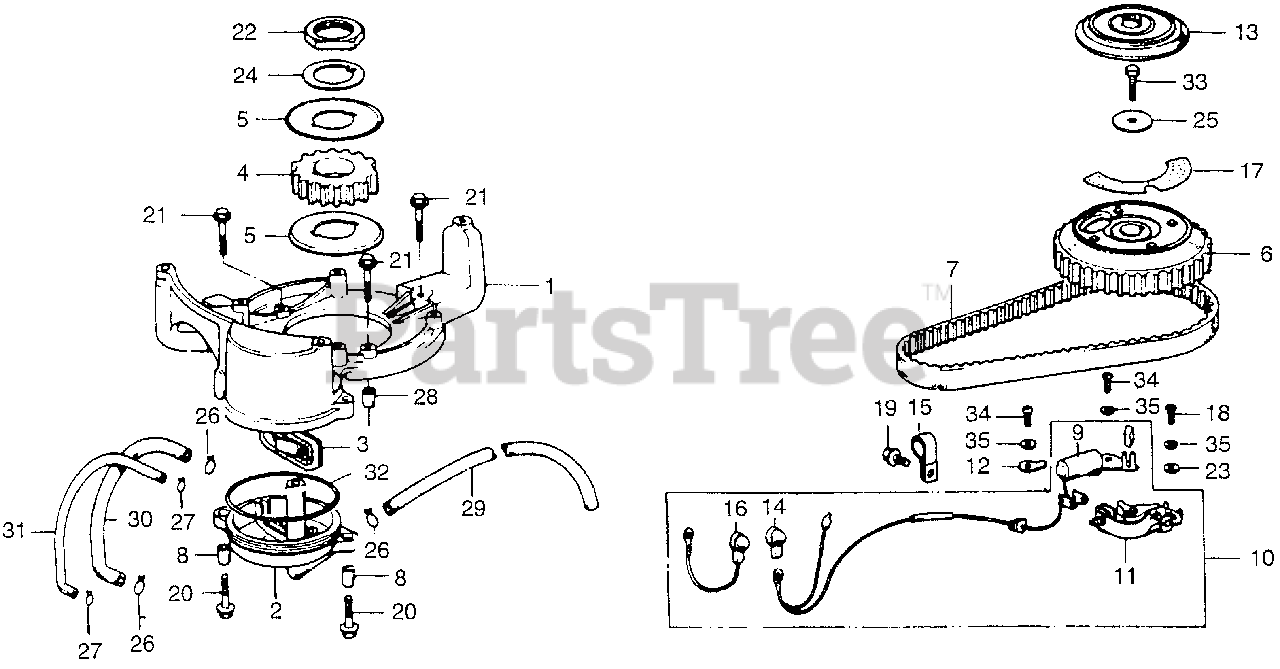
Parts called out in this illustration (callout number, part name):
1	CASE, STARTER *NH8* (DARK GRAY)
2	COVER, BREATHER
3	BODY, VALVE
4	PULLEY, TIMING
5	FLANGE, TIMING PULLEY
6	PULLEY, CAM (NOT AVAILABLE)
7	BELT, TIMING
8	COLLAR A, DISTANCE
9	CONDENSER
10	POINTS ASSY.
11	POINTS
12	PLATE, WIRE CLAMP
13	COVER, POINT
14	CAP C, CONNECTOR
15	CLAMP, WIRE
16	WIRE A, SWITCH
17	MARK, POINT
18	SCREW, PAN (5X10) (NOT AVAILABLE)
19	BOLT, FLANGE (6X12)
20	BOLT, FLANGE (6X22)
21	BOLT, FLANGE (6X28)
22	NUT, LOCK (24MM)
23	WASHER, BREAKER SETTING
24	WASHER, LOCK (24MM)
25	WASHER, WHEEL (6MM)
26	CLIP, TUBE (B12)
27	CLIP B7, TUBE
28	PIN, DOWEL (8X10)
29	TUBE B, BREATHER
30	TUBE C, BREATHER
31	TUBE, OIL RETURN
32	O-RING (62X2.5)
33	BOLT, HEX. (6X22)
34	SCREW, PAN (5X8)
35	WASHER, SPRING (5MM)
